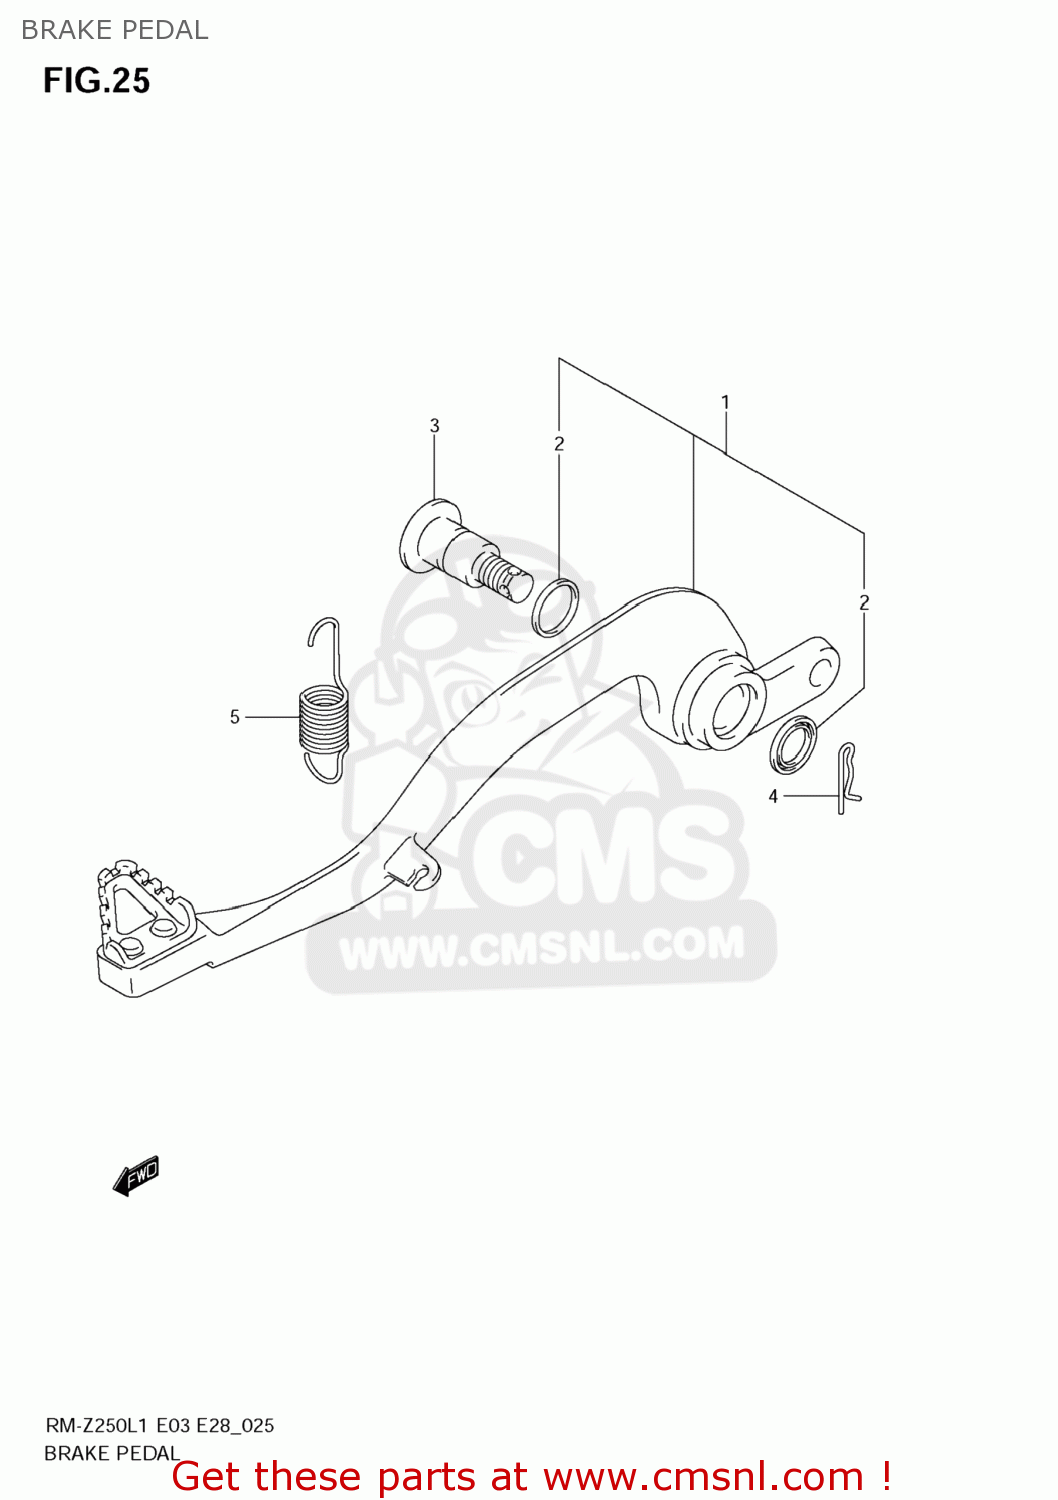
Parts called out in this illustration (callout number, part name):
1	PEDAL ASSY,BRAKE
2	SEAL,OIL(15X21X3)
3	SHAFT,BRAKE PEDAL
4	CLIP
5	SPRING
